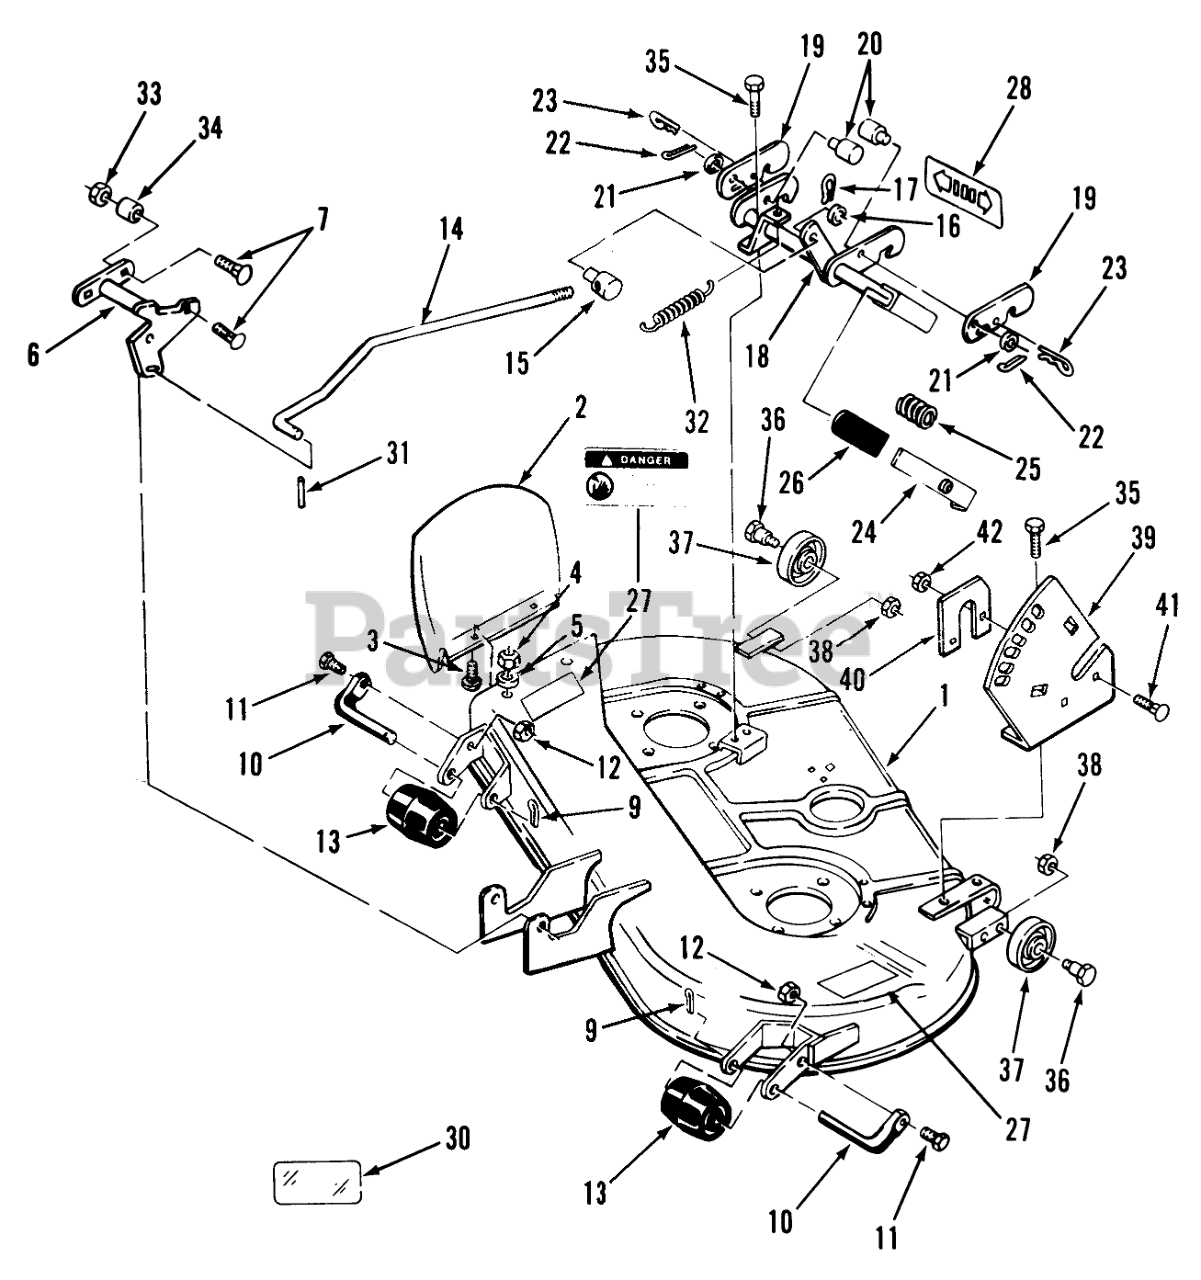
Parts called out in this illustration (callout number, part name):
1	Deck-Mower
2	Chute Extension
3	Bolt
4	Nut
5	Collar
6	ASM-FRONT LIFT R
7	Bolt-Carriage
9	Cotter Pin
10	ROLLER-SHAFT
11	Bolt
12	Nut
13	Roller
14	ASS'Y-HEIGHT ADJ R
15	STUD-TRUNION
16	Washer
17	Hairpin Cotter
18	HT. ADJ. SHAFT
19	Latch
21	Washer
22	Cotter Pin
23	Hairpin Cotter
24	LEVER ASSY
25	SPRING-COMPRESSION
27	Danger Decal
28	DECAL-HOC
30	DECAL-OVERLAY
31	SPIROL PIN
32	SPRING-EXTENSION
33	LOCKNUT-FLANGE
34	SPACER
35	Bolt
36	BOLT-SHOULDER
37	WHEEL-GAGE
38	NUT
39	Quadrant
40	PLATE-RETAINING R
41	Bolt
42	Nut
